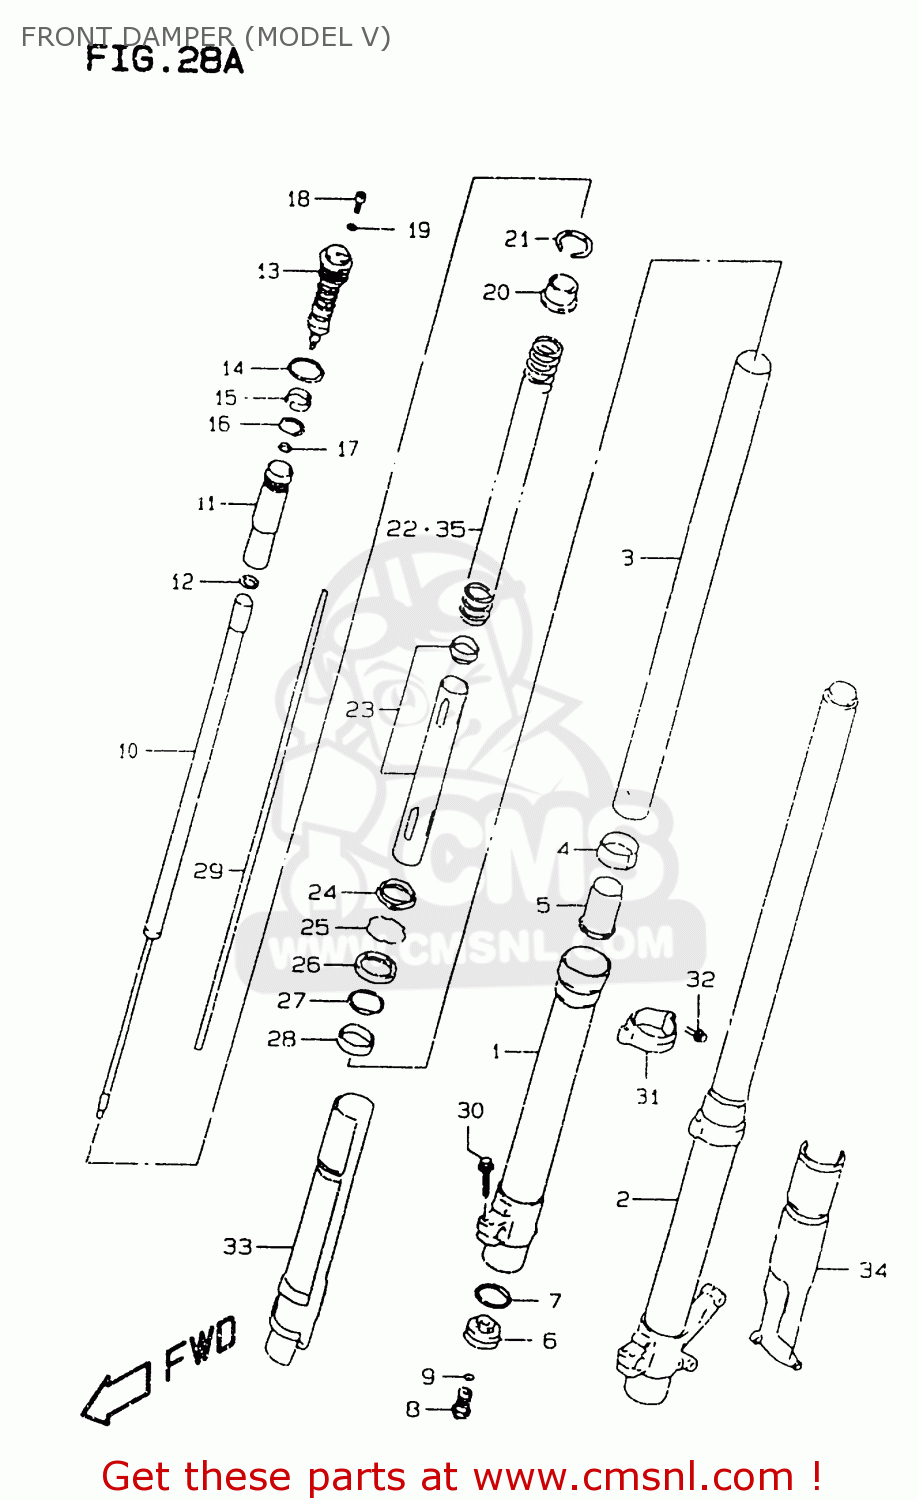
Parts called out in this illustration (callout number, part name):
1	TUBE,OUTER,RIGHT
2	TUBE,OUTER,LEFT
3	TUBE,INNER
4	BUSH,SLIDE
5	PIECE,OIL LOCK
6	PLATE,END
7	O RING
8	BOLT,CTR
9	O RING
10	ROD,FR DAMPER
11	TANK,SUB
12	O-RING
13	BOLT,FORK
14	O RING
15	BUSH,FORK BOLT SLIDE
16	O RING
17	O RING
18	BOLT,PLUG
19	O RING,PLUG
20	SPRING,STOPPER
21	RING,STOPPER
22	SPRING,FR(K=0.40)
23	COLLAR,SPRING
24	SEAL,DUST
25	RING,STOPPER
26	SEAL,OIL
27	SPACER,SEAL
28	BUSH,GUIDE
29	ROD,PUSH
30	BOLT,HANDLE HOLDER(8X35)
31	GUIDE,FR PROTECTOR,R
32	BOLT,PROTECTOR GUIDE,6
33	PROTECTOR,OUTER TUBE,R
34	PROTECTOR,OUTER TUBE,L
35	SPRING,FRONT (K=0.42)
